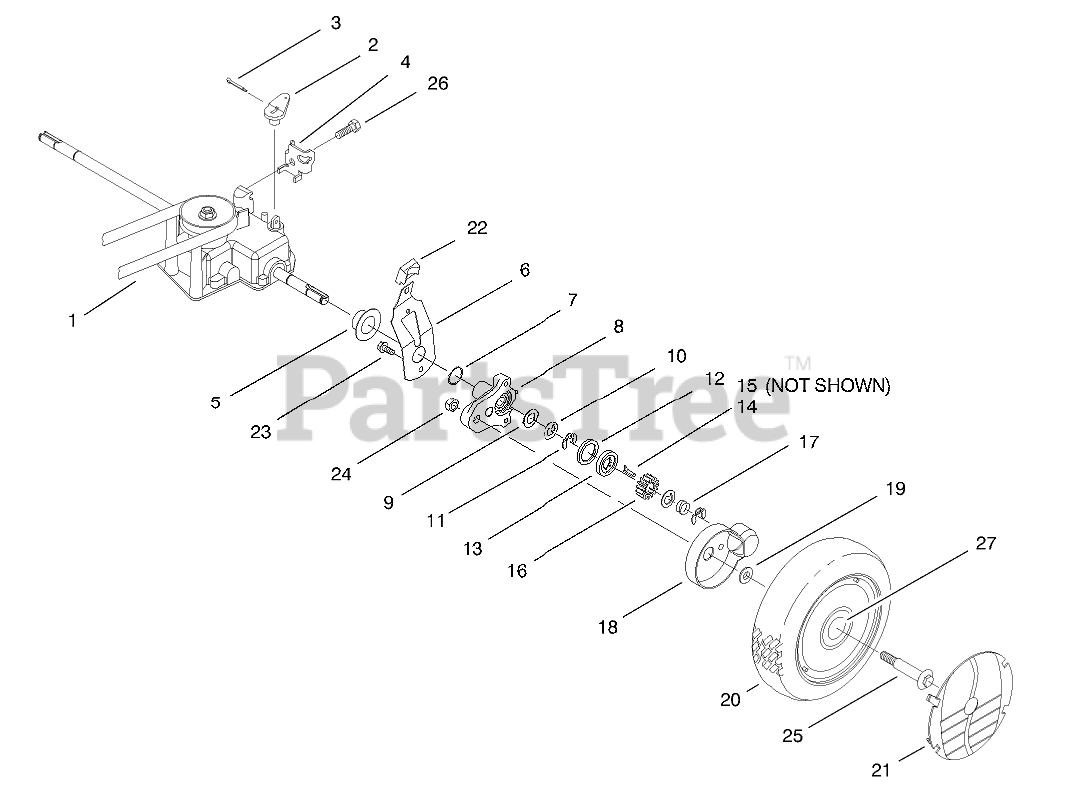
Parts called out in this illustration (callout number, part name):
1	V-BELT E
2	LEVER-SHIFT
3	PIN-COTTER
4	CLAMP-CABLE
5	CAP-END
6	SPRING ARM ASM
7	O-RING
8	PIVOT ARM ASM
9	WASHER-ARM, PIVOT
10	WASHER-THRUST, KEYED
11	RING-CLIP, LOCKING
12	RING-FRICTION
13	WASHER-CLUTCH
14	KEY-ROCKING, LH
15	KEY-ROCKING, RH
16	GEAR-PINION
17	SPRING-COMPRESSION
18	COVER-WHEEL
19	SPACER-COVER, WHEEL
20	ASM-Wheel (Incl. Ref. #27)
21	COVER-WHEEL
22	KNOB-ARM
23	SCREW-HWH
24	NUT-LOCK
25	BOLT-WHEEL
26	SCREW-HWHTF
27	BUSHING
